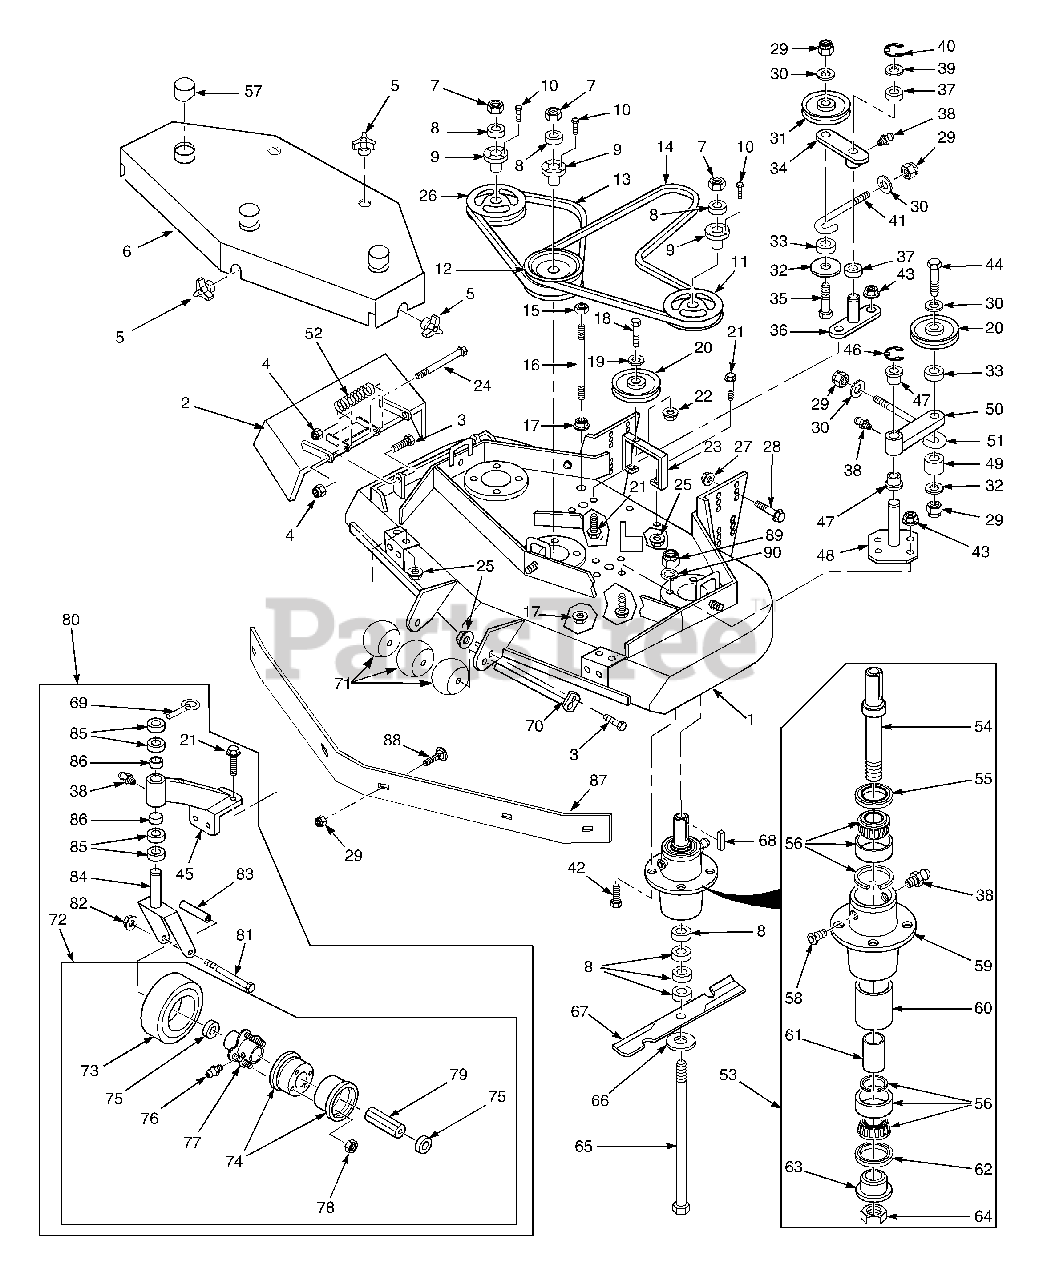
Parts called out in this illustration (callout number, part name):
1	Cutter Deck, Advantage
2	Discharge Chute, Advantage
3	Bolt, 5/16-18 x 1" Hex Head
4	Nut, 5/16-18 Elastic Stop
5	Wing Nut, 3/8-16
6	Belt Cover
7	Nut, 5/8-11 Hex Head
8	Spacer, Cutter Blade
9	Tapered Hub, 1.125 Bore
10	Bolt, 1/4-20 x 1" Hex Head Grade 8
11	Pulley, 6.95 O.D.
12	Pulley, Double Groove, 6.95/5.75 O.D.
13	Belt, R.H. Blade Drive
14	Belt, Deck Drive
15	Lock Nut,3/8-16 Hex Head
16	Stud, 3/8-16 x 6-3/4"
17	Nut, 3/8-16 Serr. Flange
18	Bolt, 3/8-16 x 2-1/4"
19	Flatwasher, 3/8 (.391 x .938 x .105)
20	Pulley, Belt Guide
21	Capscrew, 5/16-18 x 3/4 Ser. Flg. HH
22	Nut, 3/8-16 Elastic Stop
23	Idler Pulley Support
24	Bolt, Hex Head 5/16-18 x 4-1/4"
25	Nut, 5/16-18 Ser. Flg. Hex Hd.
26	Pulley, 5.75
27	Nut, 1/2-13 Ser. Flg. Hex Hd.
28	Capscrew, 1/2-13 x 1-1/4 Ser. Flg.
29	Nut, 3/8-16 Elastic Stop
30	Flatwasher, 3/8 (.391 x .938 x .105)
31	Pulley
32	Flatwasher, 3/8 (.375 x 1.50 x .060)
33	Spacer
34	Idler Arm
35	Bolt, 3/8-16 x 2-1/4"
36	Idler Pivot
37	Bushing, Bronze Oilite-3/4 ID
38	Grease Fitting, Str. 1/4-28 Self Tap.
39	Flatwasher, 3/4 ( .776 x 1.25 x .059)
40	Retaining Ring, .75 EXT 'E'
41	J-Rod Idler Pulley
42	Bolt, 5/16-18 x 1-1/2" Hex Head Gr 8
43	Nut, 5/16-18 Ser. Flange
44	Bolt, 3/8-16 x 3-1/2" Hex Head
45	Support Assembly
46	Retaining Ring, 1-1/8 EXT 'E'
47	Bushing, Bronze Oilite- 1-1/8 ID
48	Idler Pivot Support
49	Spacer
50	Idler Arm
51	J-Rod, Drive Idler
52	Spring, Chute Return
53	Spindle Assembly
54	Shaft, Cutter Spindle
55	Seal, 2.00 O.D. x 1.50 Bore
56	Bearing Assembly
57	Shield, Spindle
58	Relief Fitting, Cutter Spindle
59	Spindle Housing
60	Spacer, Outside
61	Spacer, Inside
62	Seal, 2.00 O.D. x 1-5/8 Bore
63	Spindle Bushing Bottom
64	Nut, 1-1/16-18 UNEF-2B
65	Bolt, 5/8-11 x 9-1/2"
66	Flatwasher, 5/8 (.688 x 1.75 x .134)
67	Cutter Blade, 24" Standard
68	Key, 1/4 x 1/4 x 2"
69	Quick Pin
70	Shaft, Roller
71	Guide, Roller
72	Wheel Assy., Caster
73	Tire Only, Caster Wheel
74	Rim Pair, Caster Wheel
75	Retainer, Caster Wheel
76	Grease Fitting, 45 Deg. 1/4-28
77	Hub Assy. W/Bolts, Caster Wheel
78	Tapered Hex Nut, 5/16-18
79	Roller Bearing, Caster Wheel
80	Caster Wheel Assembly
81	Bolt, 1/2-13 x 5-1/2" Hex Head
82	Nut, 1/2-13 Elastic Stop
83	Sleeve, Caster Wheel Bearing
84	Caster Yoke
85	Spacer, Caster Yoke 1/2"
86	Bushing, 7/8 x 1" Flanged
87	Baffle, Custom Cut 72A
88	Bolt, Carriage 3/8-16 x 1"
89	Nut, Elastic Stop 5/16-18 Grade 8
90	Lock Washer, 5/16"
